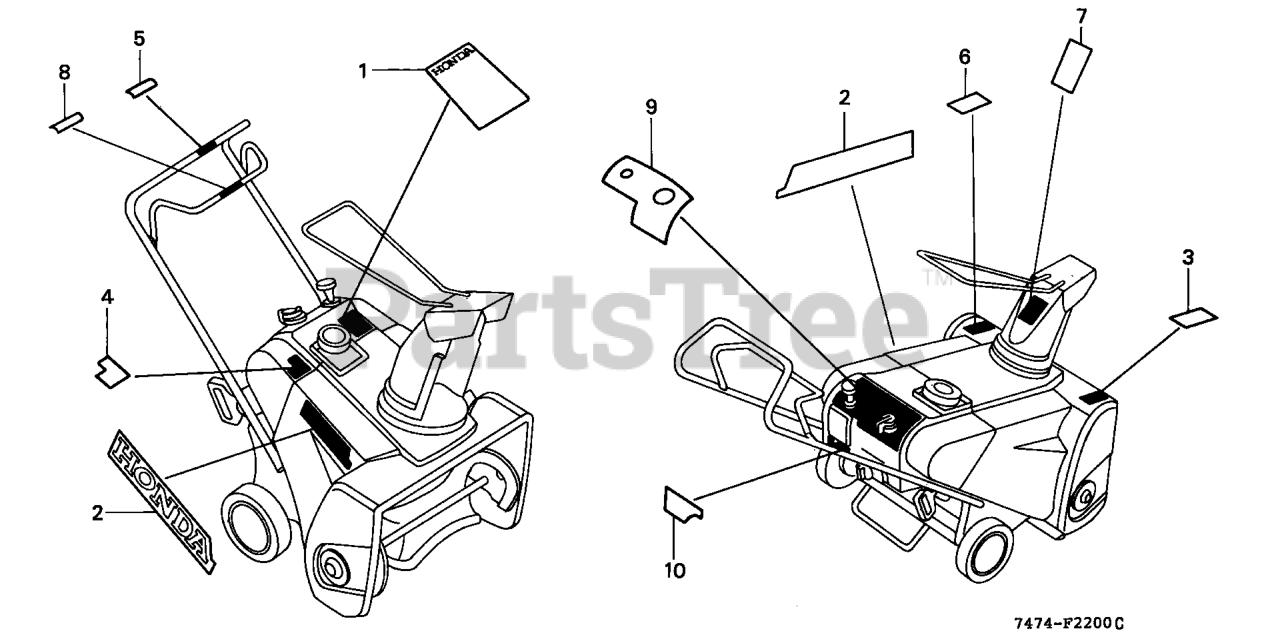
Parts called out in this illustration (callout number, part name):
1	EMBLEM (HS621)
2	MARK,HONDA
3	LABEL, WARNING (ENGLISH)
4	LABEL, FUEL WARNING (ENGLISH)
5	MARK, CLUTCH OPERATION (ENGLISH)
6	MARK, HOUSING DANGER (ENGLISH)
7	MARK, DISCHARGE DANGER (ENGLISH)
8	MARK, SAFETY YELLOW
9	MARK, CONTROL OPERATION (ENGLISH)
10	LABEL, OIL CAUTION (ENGLISH)
